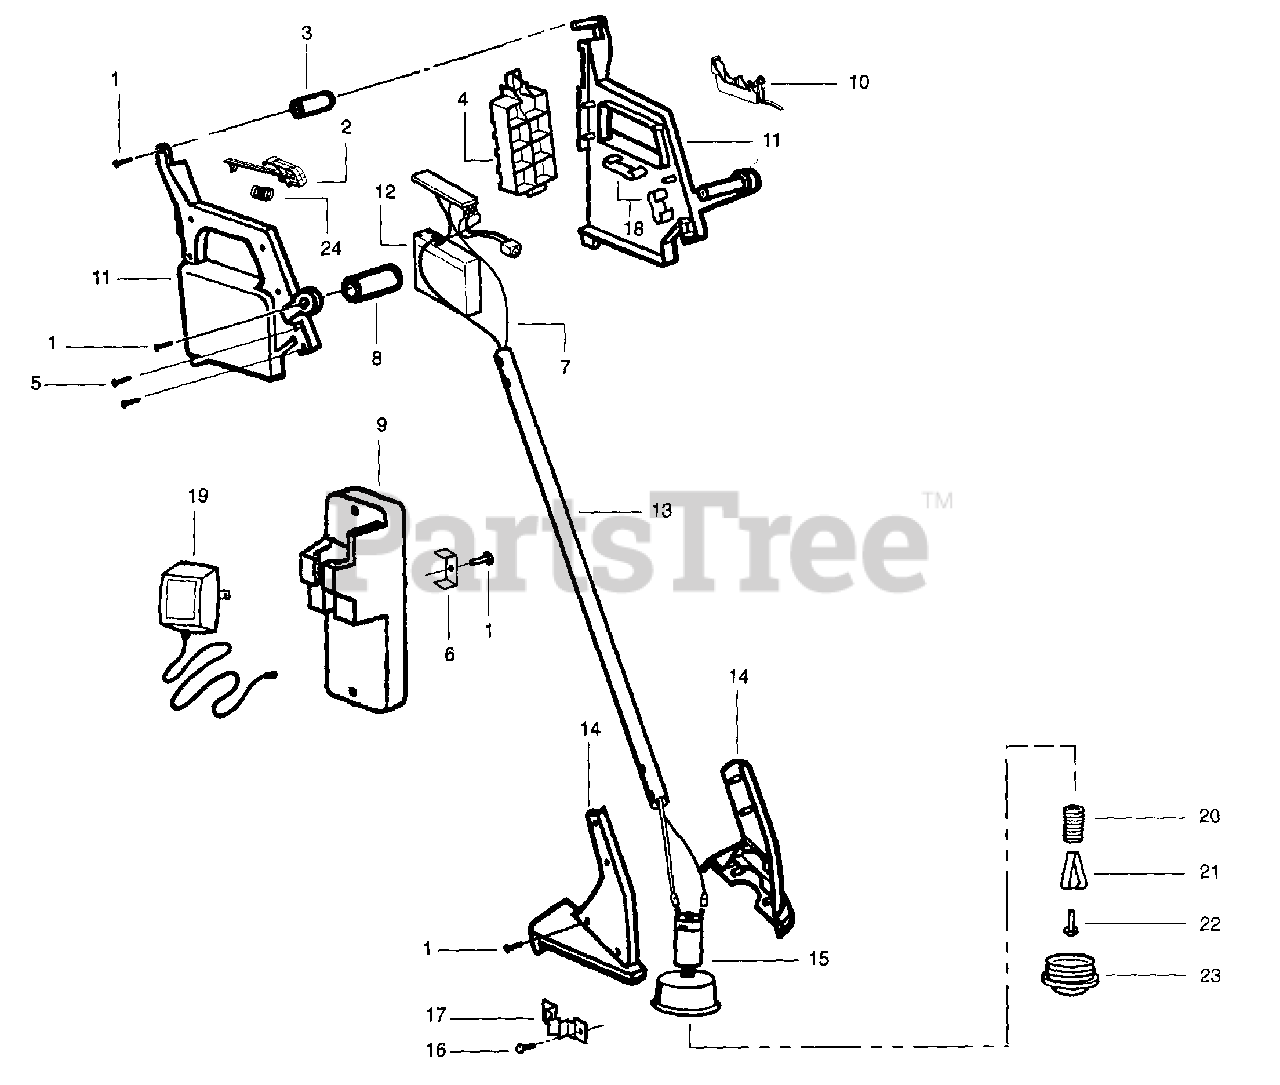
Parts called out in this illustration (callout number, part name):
2	Trigger Lockout
3	Wrist Support Cushion
4	Battery Door
6	Probe - Clamp
7	Wire Harness Ass'y.
8	Assist Handle Cushion
9	Wall Bracket
10	Trigger Switch
11	Battery Hsg. Set
13	Tube w/ Warning Decal
14	Motor Hsg. Set w/ Line Limiter
15	Motor/Hub Ass'y.
17	Clamp - Motor
18	Battery Spring
21	Retainer Spring
22	Screw w/Washer
23	Spool w/Line
24	Lockout Spring
